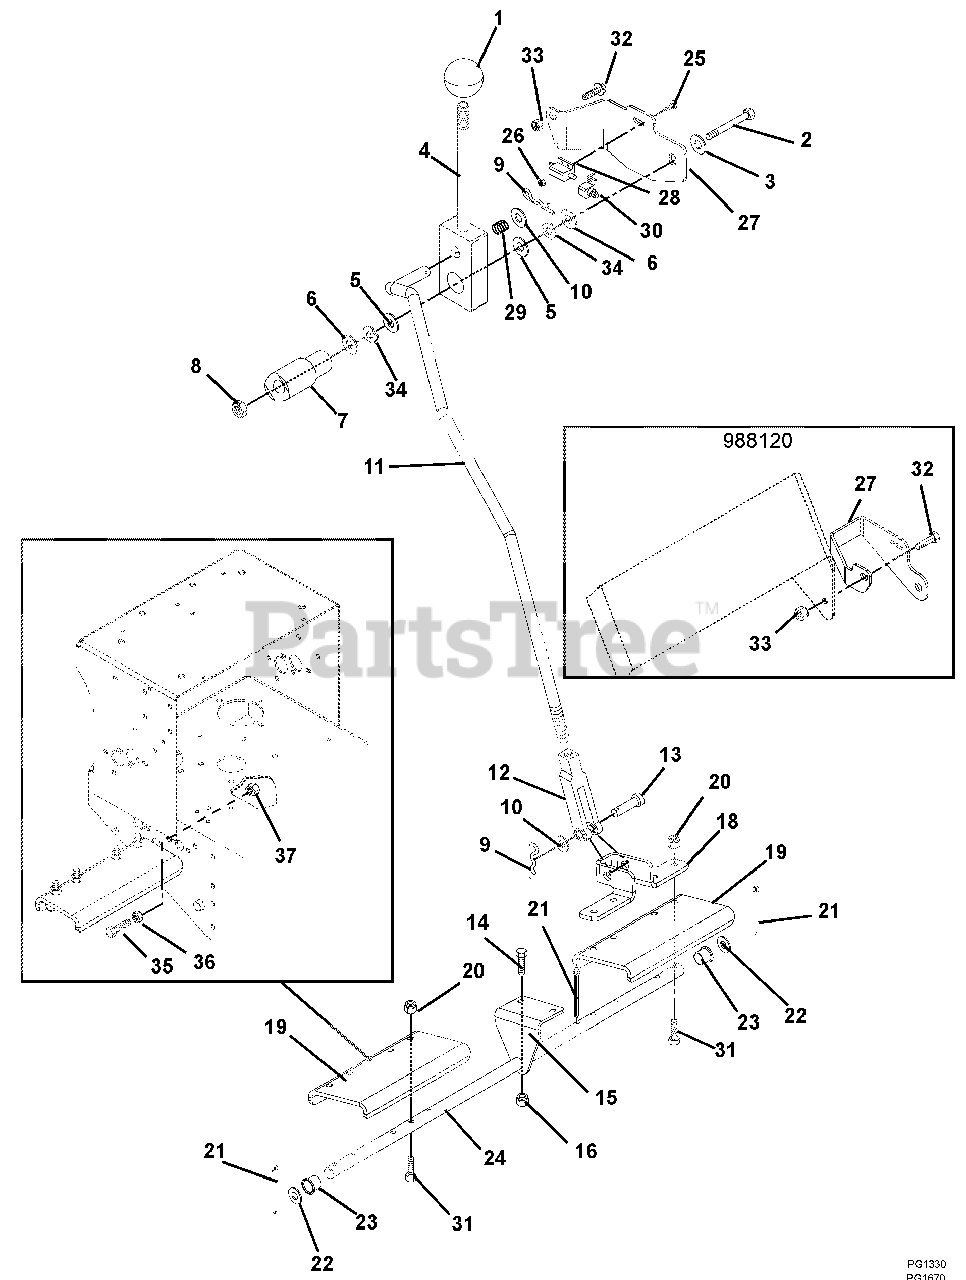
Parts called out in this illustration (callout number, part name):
1	Knob, Ball-Black 1-.41, .375-1
2	Bolt, Hex .44-14 x 4.5 Grade 5
3	Washer, Flat-Steel .50 x 1.25 x .083
4	Weldment, Handle
5	Washer, Flat-Nylon .76 x 1.25 x .030
6	Washer, Flat-Steel .76 x 1.38 x .062
7	Pivot, Brake
8	Nut, Locking-Hex .44-14
9	Pin, Hair Internal .08 x .18 x 1.18
10	Washer, Flat-Steel .406 x .812 x .065
11	Rod, Brake (105, 108, 123, 126)
12	Clevis,.38-24 Adjustable
13	Pin, Clevis .37 x 1.75
14	Bolt, Hex .38-16 x 1.00 Grade 5
15	Bracket, Brake Shaft
16	Nut, Locking-Nylon .38-16
17	Bolt, Hex .25-20 x 1.50 Grade 5
18	Brake, Arm
19	Pad, Brake
20	Nut, Locking-Nylon .25-20
21	Pin-Cotter .12 x 1.00
22	Washer, Flat-Steel .656 x 1.31 x .095
23	Bushing-Flange .63 x 1.00 x .625 Nylon
24	Brake, Shaft
25	Screw, Machine 10-24 x .75 Hex Washer Head
26	Nut, Locking-Nylon 10-24 with Insert
27	Bracket, Parking Brake Switch (105, 108, 123, 126)
28	Switch, Interlock
29	Spring, Compression .045 x .60 x .75
30	Boot, Rubber
31	Bolt, Hex .25-20 x 1.25 Grade 5
32	Bolt, Serrated Hex Flange Washer Head .25-20 x .75 (105, 108, 123, 126)
33	Nut, Locking-Top-Flange .25-20 (105, 108, 123, 126)
34	Washer, Wave .076 x 1.12 x .080
35	Bolt, Hex .38-16 x 1.75 Grade 5
36	Nut, Hex .38-16
37	Nut, Locking-Nylon .38-16
